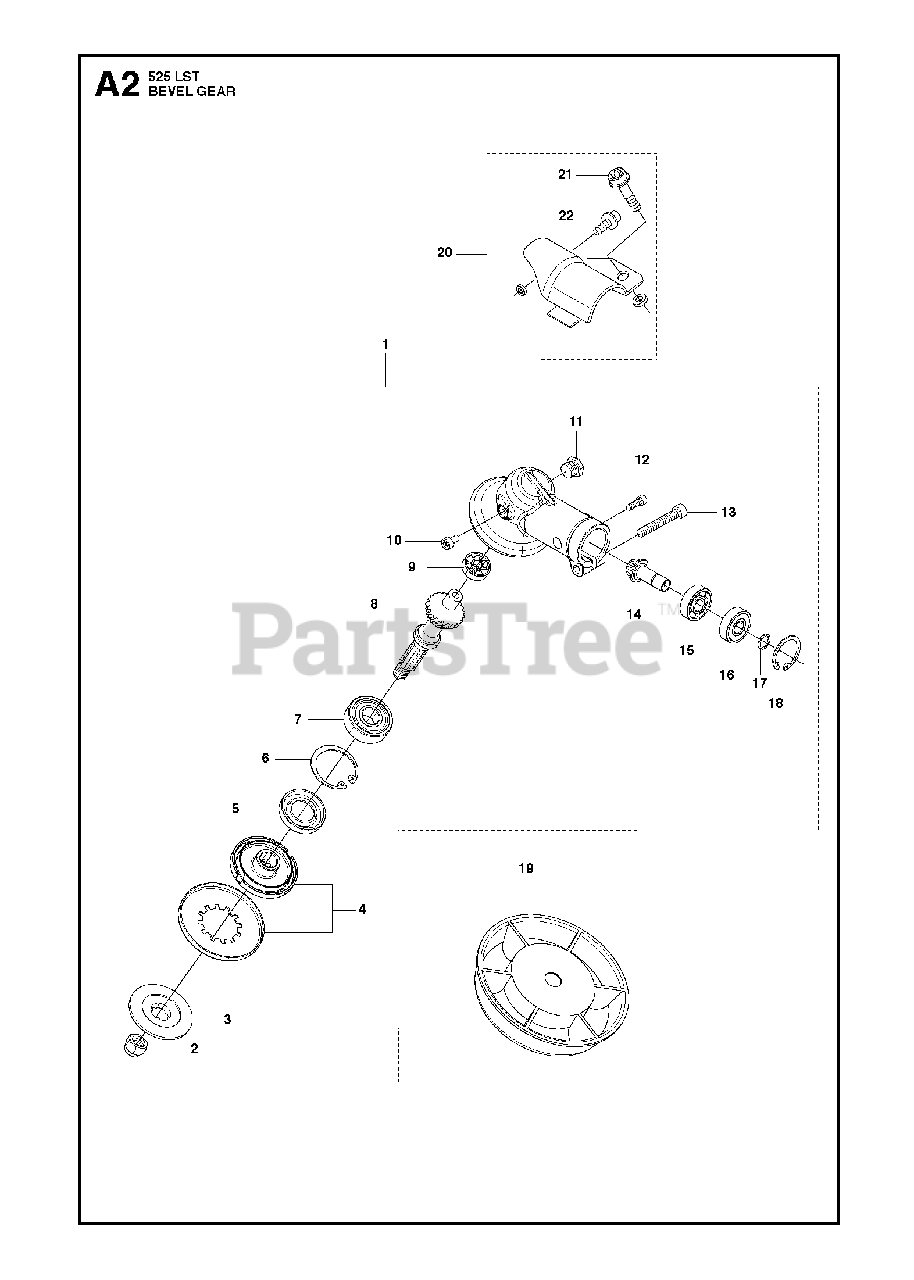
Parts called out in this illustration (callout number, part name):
1	BEVEL GEAR ASSY
2	GEARHEAD NUT - BRUSHCUTTER
3	SUPPORT FLANGE
4	DRIVER ASSY
5	SEAL
6	RING
7	BEARING***
8	GEAR ASSY
9	BEARING (RPLS T330013520)
10	BOLT
11	SCREW M10X1.25 T27
12	BOLT (RPLS T495051010-11)
13	BOLT M5X20 T27
14	PINION HIGH REDUCTION RATIO
15	BEARING
16	BEARING
17	RING
18	RP_RING
19	SUPPORTING CUP
20	ASSY CLAMP
21	BOLT
22	BOLT (RPLS T495051010-11)
